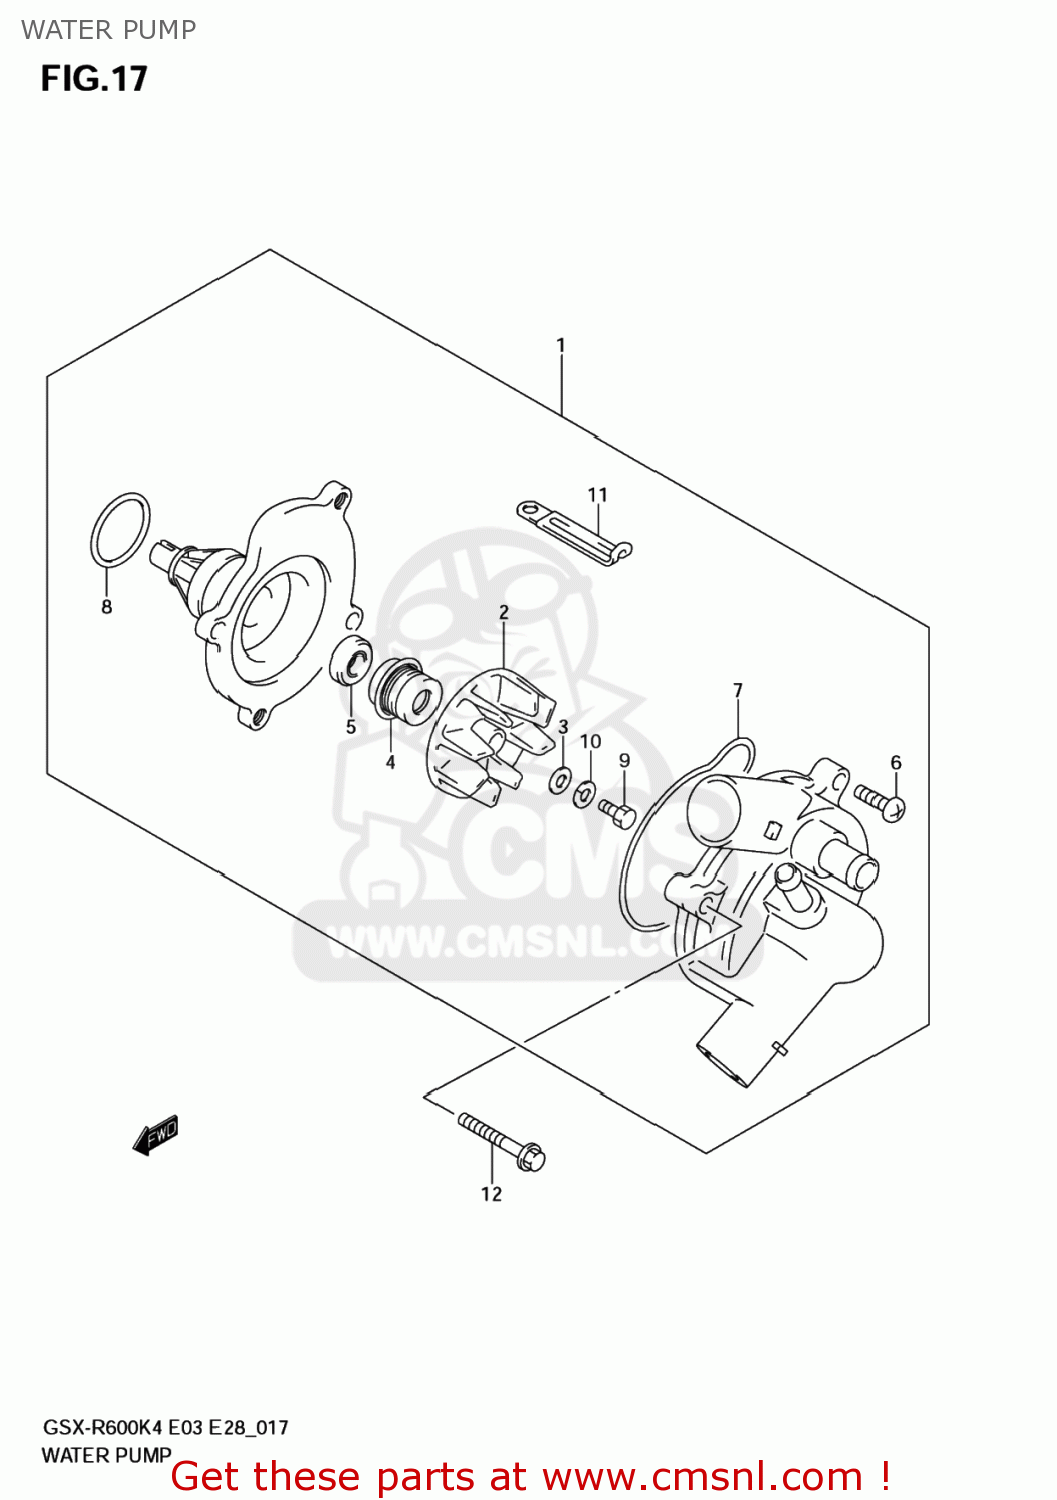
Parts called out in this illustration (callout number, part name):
1	PUMP ASSY,WATER
2	IMPELLER
3	GASKET(6X15X2.2) (NAS)
4	SEAL,MECHANICAL
5	SEAL,OIL(10X21X5)
6	SCREW 6X16
7	O RING
8	O RING,WATER PUMP HOLDER
9	BOLT(6X13)
10	WASHER
11	CLAMP(L:45)
12	BOLT
